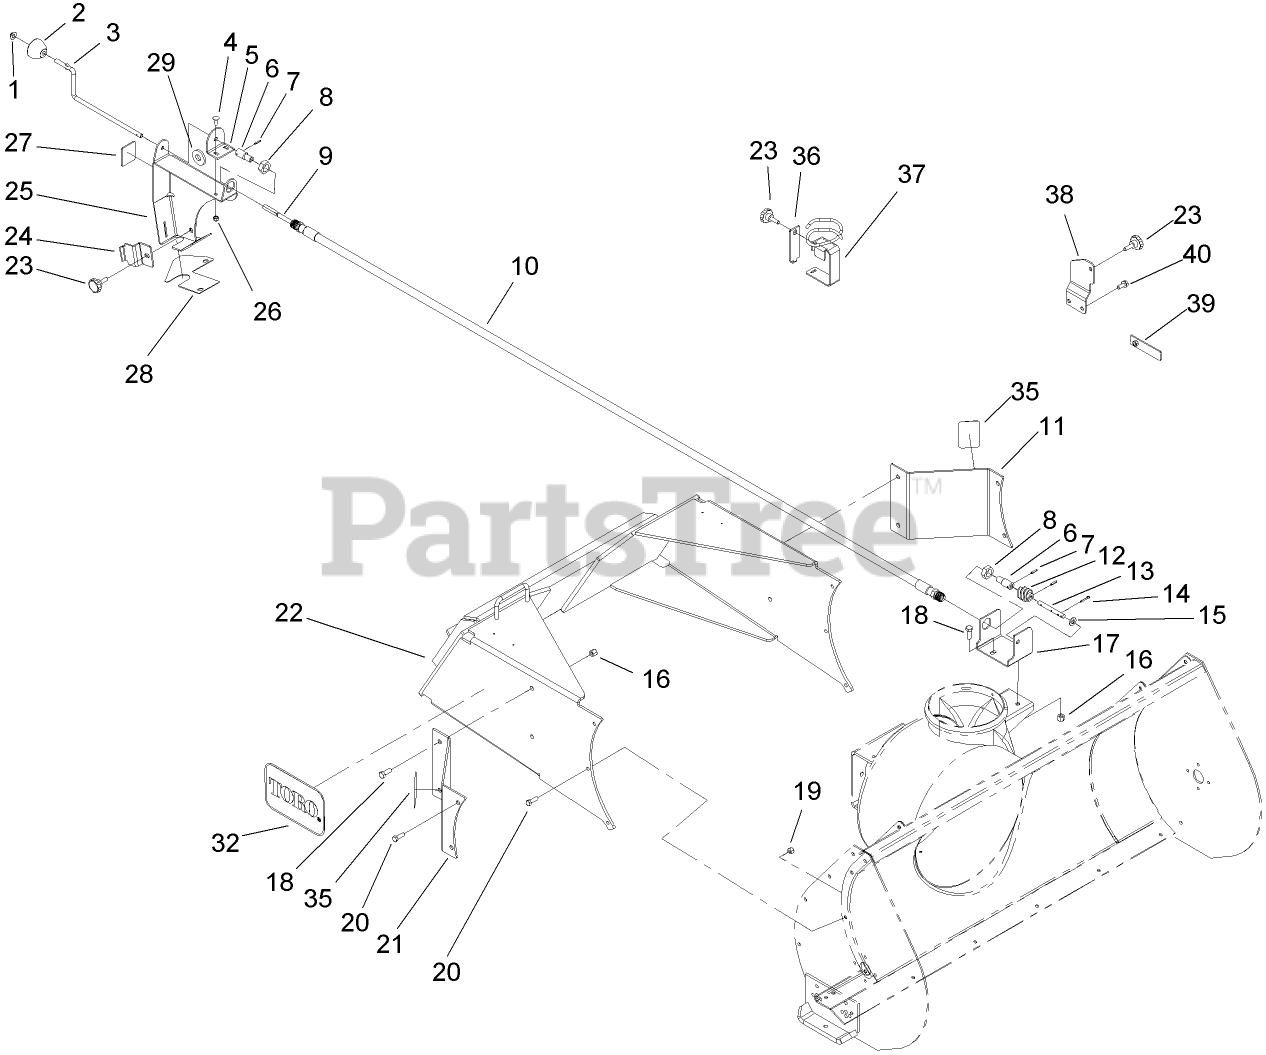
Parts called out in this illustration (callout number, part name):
1	NUT-PUSH
2	KNOB-CHUTE
3	ROD-CONTROL, CHUTE
4	BOLT-CARR
5	BRACKET-ROD, SUPPORT
6	COUPLER
7	PIN-SPRING
8	LOCKNUT
9	SHAFT-FLEXIBLE
10	HOSE ASM
11	PLATE-EXTENSION, LH
12	GEAR-WORM, CHUTE
13	SHAFT-GEAR, WORM
14	PIN-COTTER
15	WASHER-FLAT
16	NUT-LOCK, NI
17	BRACKET-GEAR, WORM
18	SCREW-HH
19	NUT-LOCK, NI
20	SCREW-HH
21	PLATE-EXTENSION, RH
22	SNOWTHROWER MOUNT ASM
23	KNOB-CONTROL, CHUTE
24	BRACKET-CLAMP
25	BRACKET-CONTROL, CHUTE
26	NUT-LOCK, NI
27	DECAL-CHUTE DIRECTION
28	FOAM-CHUTE, CONTROL
29	WASHER-FLAT
32	DECAL
35	REFLECTOR
36	BRACKET-RETAINER, CLAMP
37	HOSE RETAINER ASM
38	BRACKET,CLAMP
39	PLATE-RETAINER
40	SCREW-HWHTF
